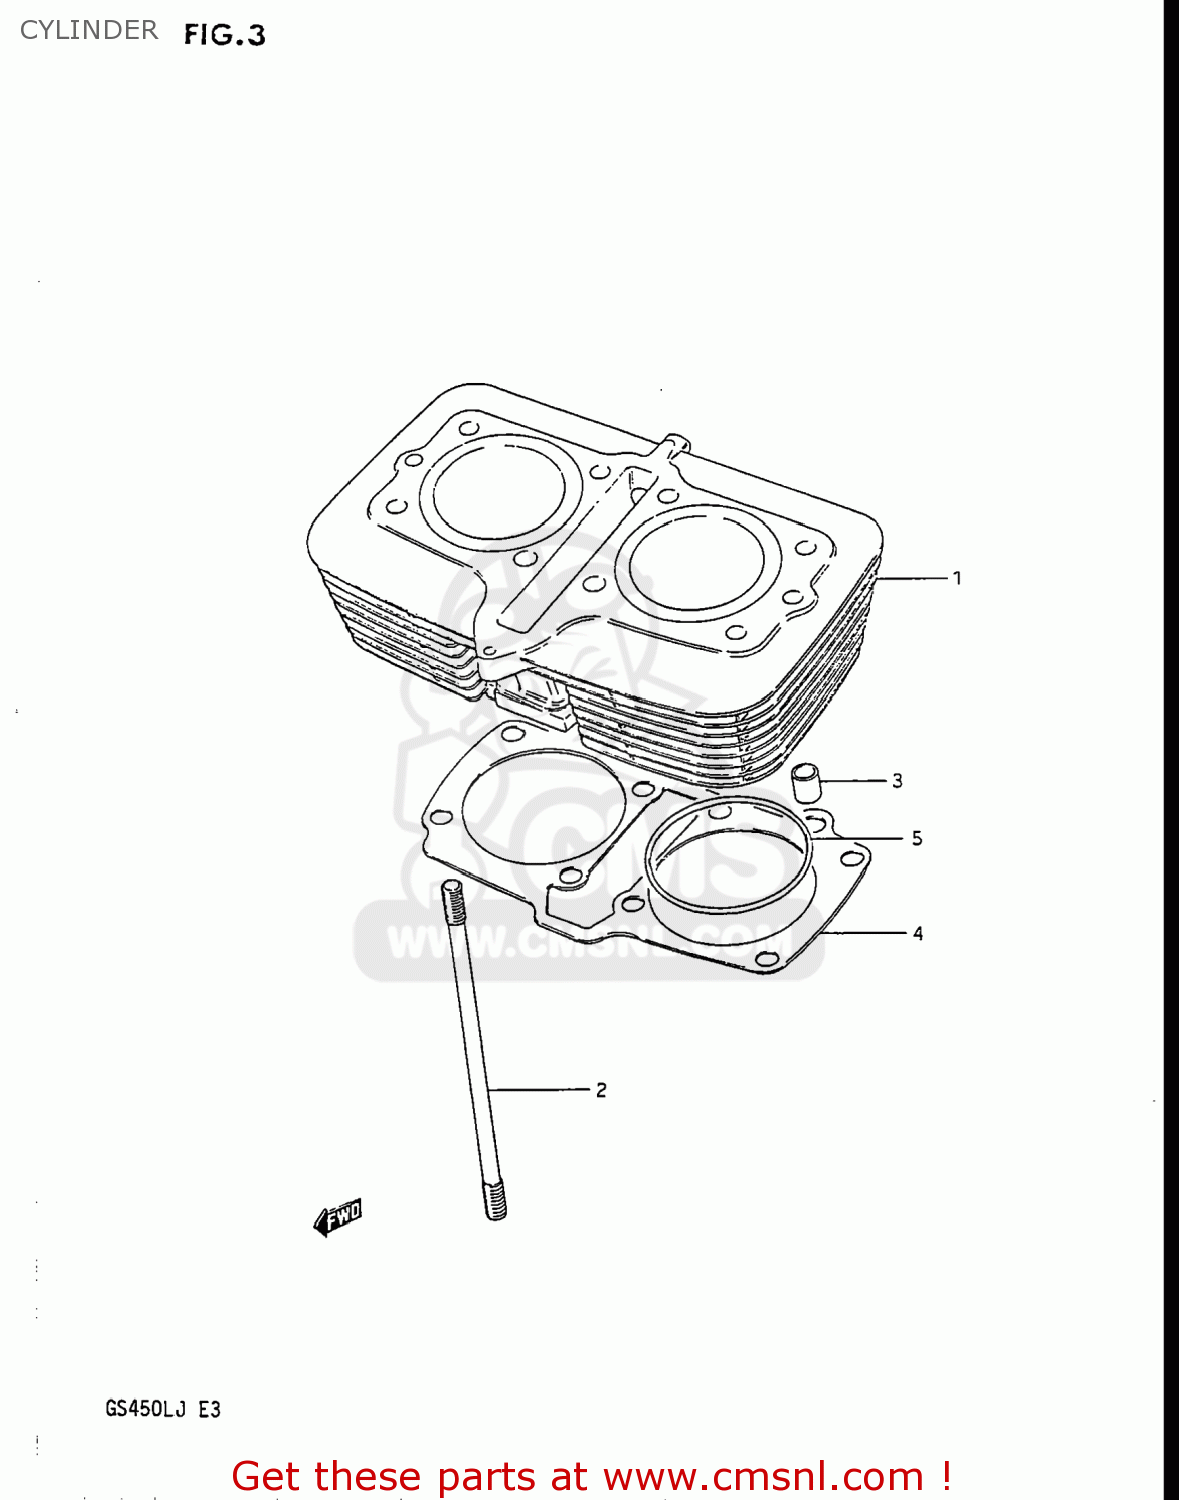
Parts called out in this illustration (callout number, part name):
1	CYLINDER
2	STUD
3	PIN
4	GASKET,CYLINDER (MCA)
5	O RING(D:2,ID:74)
